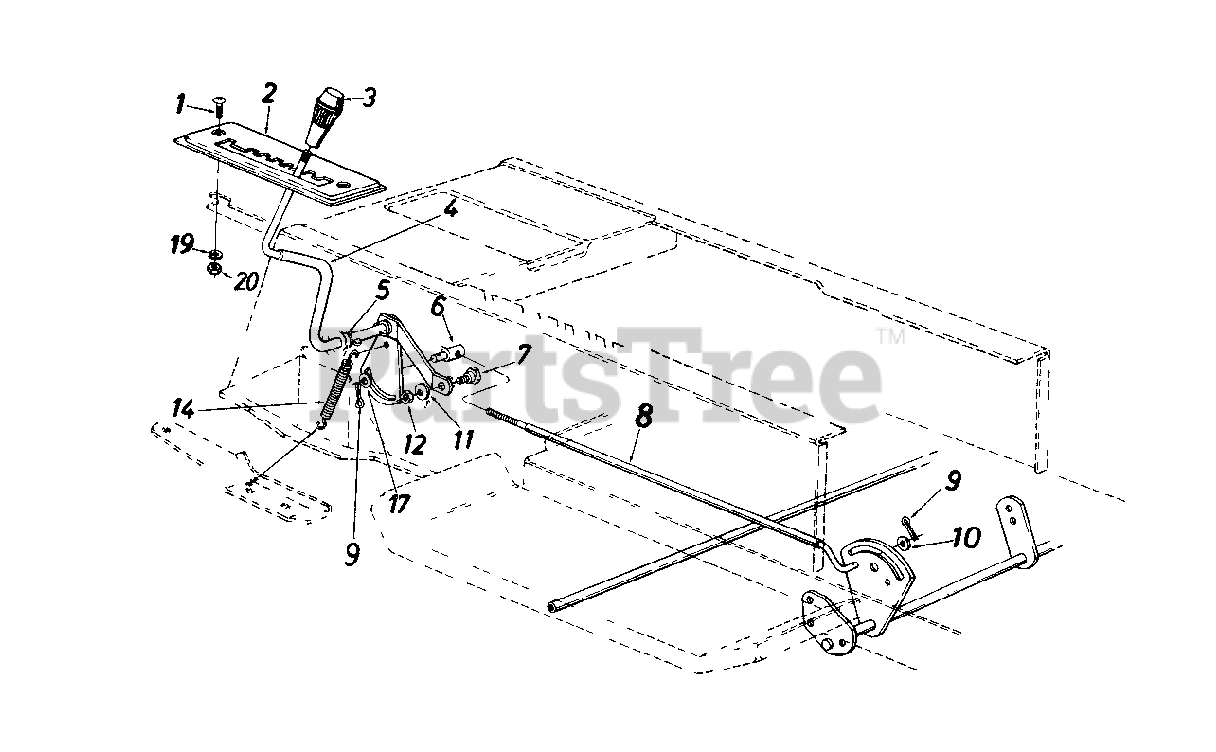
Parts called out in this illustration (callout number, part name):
1	Truss Mach. Scr. 1/4-20 x .75" Lg.
2	8-Speed Selector Plate
4	Speed Selector Lever Ass'y.
5	Flat Washer .53" I.D. x .93"
6	Ferrule 3/8-24 x .37" Dia.
7	Shoulder Bolt
8	Speed Control Link
9	Cotter Pin 3/32" Dia. x 1.0"
10	Fl-Wash. .469" I.D. x .88"
11	L-Wash. 5/16" I.D.
12	Hex Nut 5/16-18 Thd. (Gr. 5)
14	Spring .38" O.D. x 3.18" Lg.
17	Fl-Wash. .385" I.D. x 7/8"
19	L-Wash. 1/4" I.D.
20	Hex Nut 1/4-20 Thd. (Gr.5)
